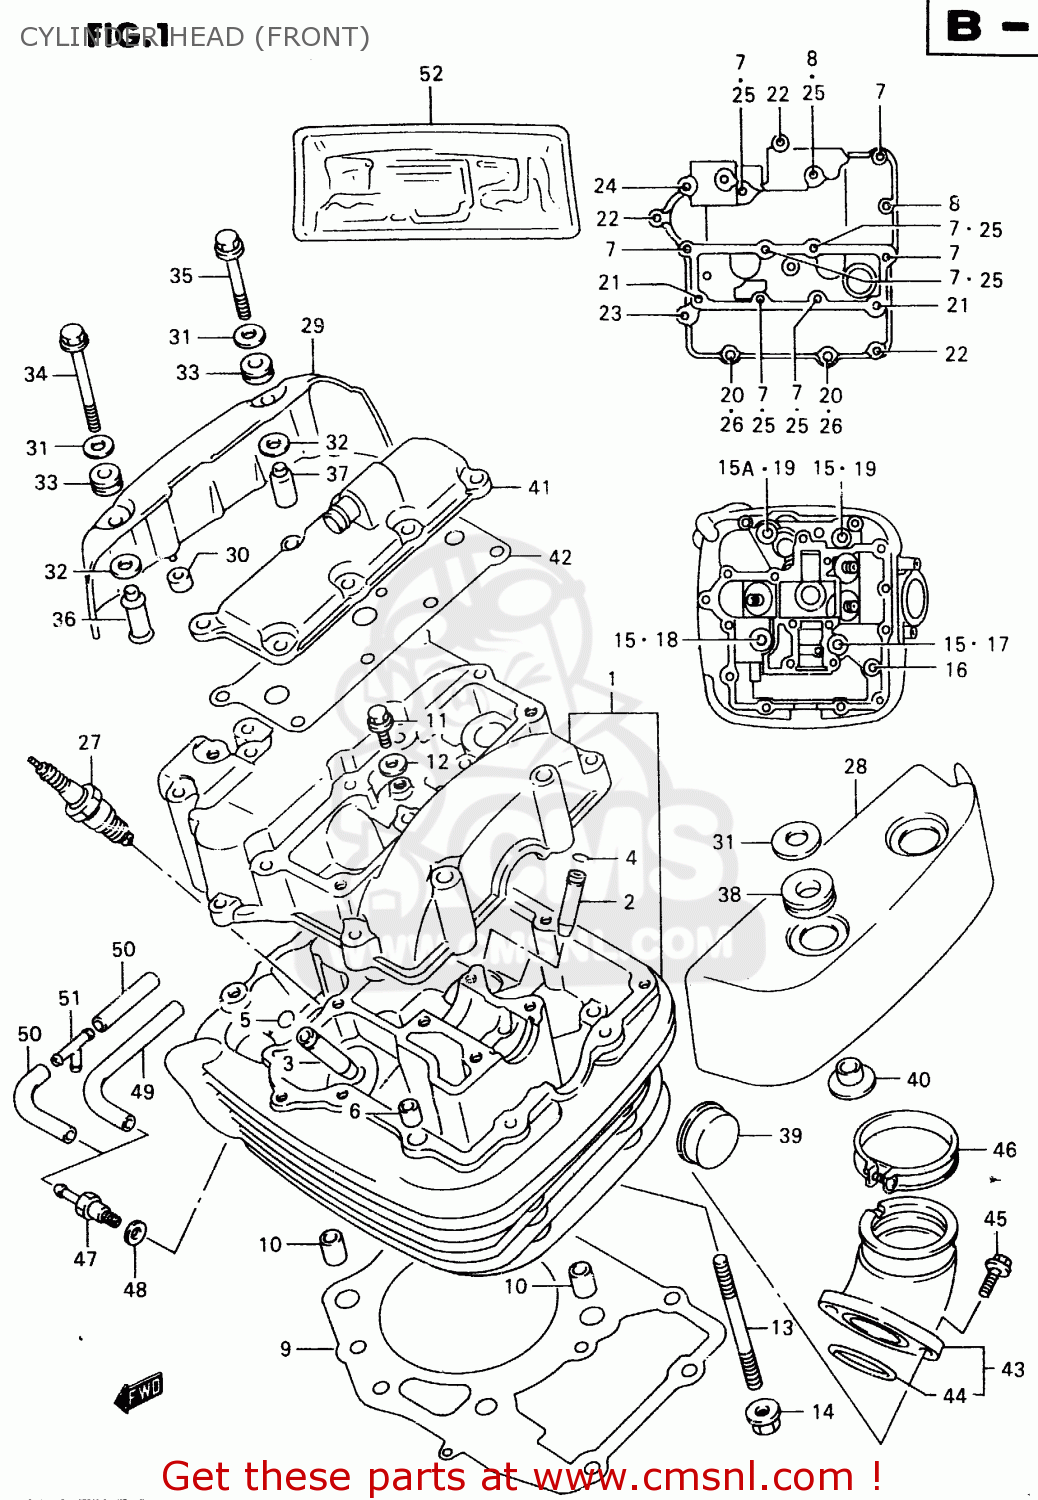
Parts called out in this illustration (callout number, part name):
1	HEAD ASSY,CYLINDER FR
2	GUIDE,INTAKE VALVE
3	GUIDE,INTAKE VALVE
4	RING,SNAP
5	RING,SNAP
6	PIN(6.2X8X11)
7	BOLT(6X60)
8	BOLT(6X55)
9	GASKET,CYLINDER HEAD FR (NAS)
10	PIN
11	BOLT
12	GASKET(6.2X13X1.2) (NAS)
13	BOLT,STUD
14	NUT
15	WASHER (10.5X22X2.3)
15A	GASKET(10.5X22X2) (NAS)
16	BOLT(8X70)
17	BOLT(10X180)
18	BOLT(10X190)
19	BOLT(10X200)
20	BOLT(8X268)
21	BOLT
22	BOLT
23	BOLT
24	BOLT
25	GASKET(5.8X13X1.2) (NAS)
26	WASHER(8.5X24X1.6)
27	PLUG,SPARK(DPR7EA-9)
28	CAP,CYLINDER HEAD COVER FR,L
29	CAP,CYLINDER HEAD COVER FR,R
30	CUSHION,R CAP
31	WASHER(6.5X18X1.6)
32	WASHER(9.5X20X1)
33	CUSHION
34	BOLT
35	BOLT
36	SPACER,CYL HEAD COVER CAP NO.1
37	SPACER,CYL HEAD COVER CAP NO.2
38	CUSHION
39	PLUG(OD:30)
40	BUSH
41	COVER,BREATHER
42	GASKET,BREATHER COVER (NAS)
43	PIPE ASSY,INTAKE FR
44	O RING(D:1.9,ID:40.7)
45	BOLT(6X16)
46	CLAMP
47	BOLT UNION
48	GASKET(6.2X13X1.2) (NAS)
49	HOSE(3.5X7.5X600)
50	HOSE(3.5X7.5X600)
51	3 WAY
52	GASKET SET (NAS)
